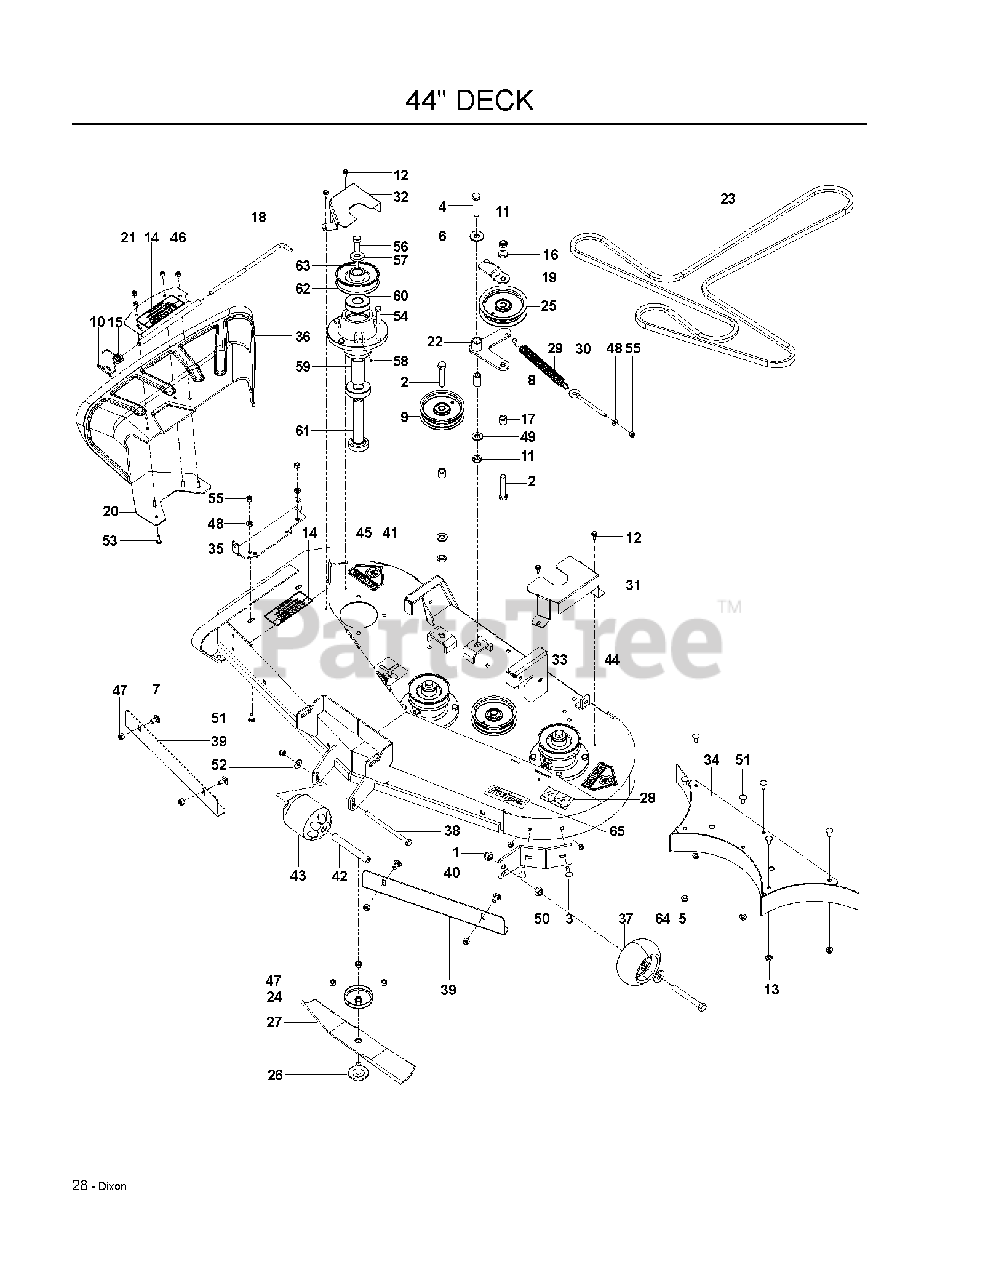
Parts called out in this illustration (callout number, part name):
1	NUT 1/2-13 HEX NYLOC ZD
2	HCS 1/2C X 2 3/4
3	RHSSNB 5/16C X 1.0
4	HEX SCREW 1/2-13 X 2.5" GR 5
5	HCS 1/2-13 X 4 GR 5 ZD
6	WASH USS FLAT 1/2
7	RHSNB 3/8-16 X 3/4 GR5 ZD
8	BUSHING DIXON 1080
9	PULLEY IDLER
10	PIN, COTTER 1 3/4
11	NUT, 1/2-13 THIN PROF NYL
12	SCREW, TAP & DR #12-14 X 3/4
13	5/16-18 FLANGED L-NUT
14	DECAL, DANGER
15	SPRING, TORSION
16	HD PULLEY SPACER
17	BUSHING
18	DEFLECTOR PIN
19	BELT GUARD BLK
20	DEFLECTOR BRKT
21	DEFLECTOR MT BRKT
22	IDLER WLDT.
23	V-BELT 142
24	TRASH GUARD
25	IDLER PULLEY
26	BLADE BOLT
27	BLD 44" HI LIFT FUS
28	DECAL, DECK 44"
29	SPRING, DECK BELT
30	EYE BOLT 4.5`
31	PULLEY GUARD
32	PULLEY GUARD
33	HUB ASM
34	44 W-BAFFLE WLDT.
36	44 DEFLECTOR
37	GAUGE WHEEL
38	BOLT 3/8 X 6 GR5
39	BLOW-BY BAFFLE
40	ROLLER BRKT.
41	DECAL, BELT ROUTING (18656)
42	BUSHING
43	ROLLER 3-3/4 DIA. X 4-1
44	DECK W/DECALS - SZ44
45	DECAL, CPSC
46	NUT 1/4-20 NYLOC
47	NUT 3/8-16 NYLOC
48	FLAT WASHER 5/16 SAE
49	WASHER 1/2" FLAT
50	NUT HEX 1/2
51	BOLT 5/16C X 3/4" CARRIAGE
52	WASHER 3/8 FLAT
53	HCS 1/4C X 3/4 HCS
54	HCS 3/8C X 1 1/2
55	NUT 5/16 NYLOC
56	1/2-20 UNF X 1 1/4 HHBLT
57	WASHER .525 X 1.375 X .25
58	ZERK, 3/16, DRIVE IN
59	HUB SPACER-2.349
60	BEARING - 6305 - 2RS
61	SHAFT 50S
62	V-PULLEY
63	OUTER SHAFT KEY
64	WASH USS FLAT 1/2
65	DECAL, FUSION
